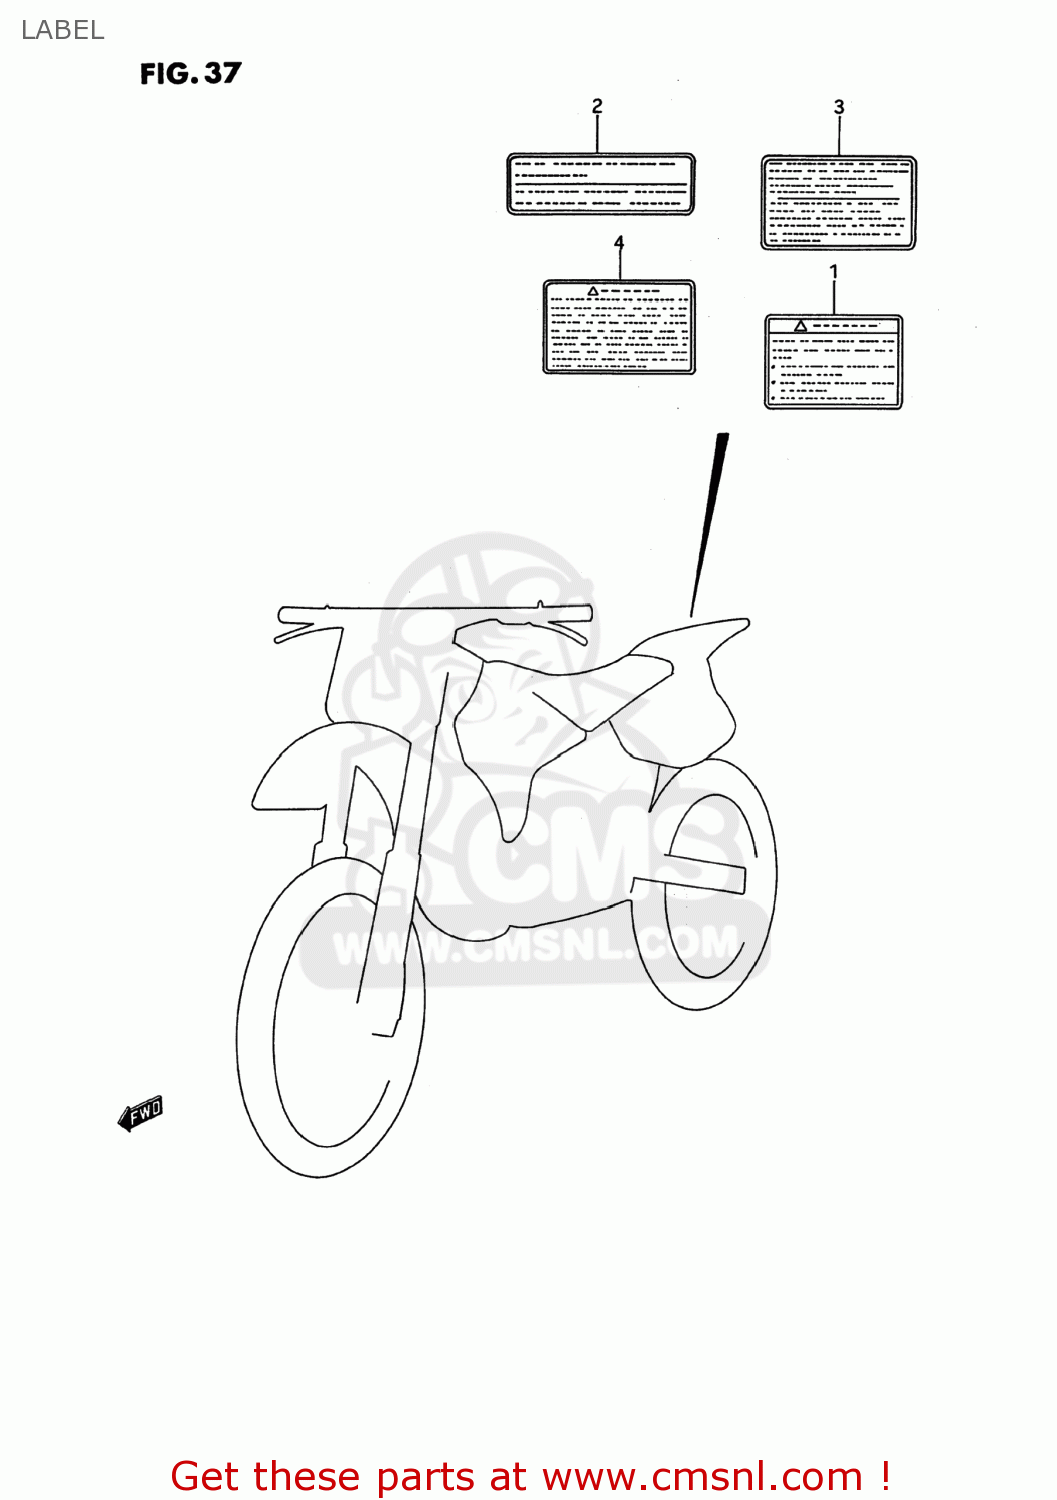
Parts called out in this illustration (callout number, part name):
1	LABEL
2	LABEL,WARNING NO.2
3	LABEL,WARNING
4	LABEL,WARNING
5	OWNER SERVICE MANUAL
